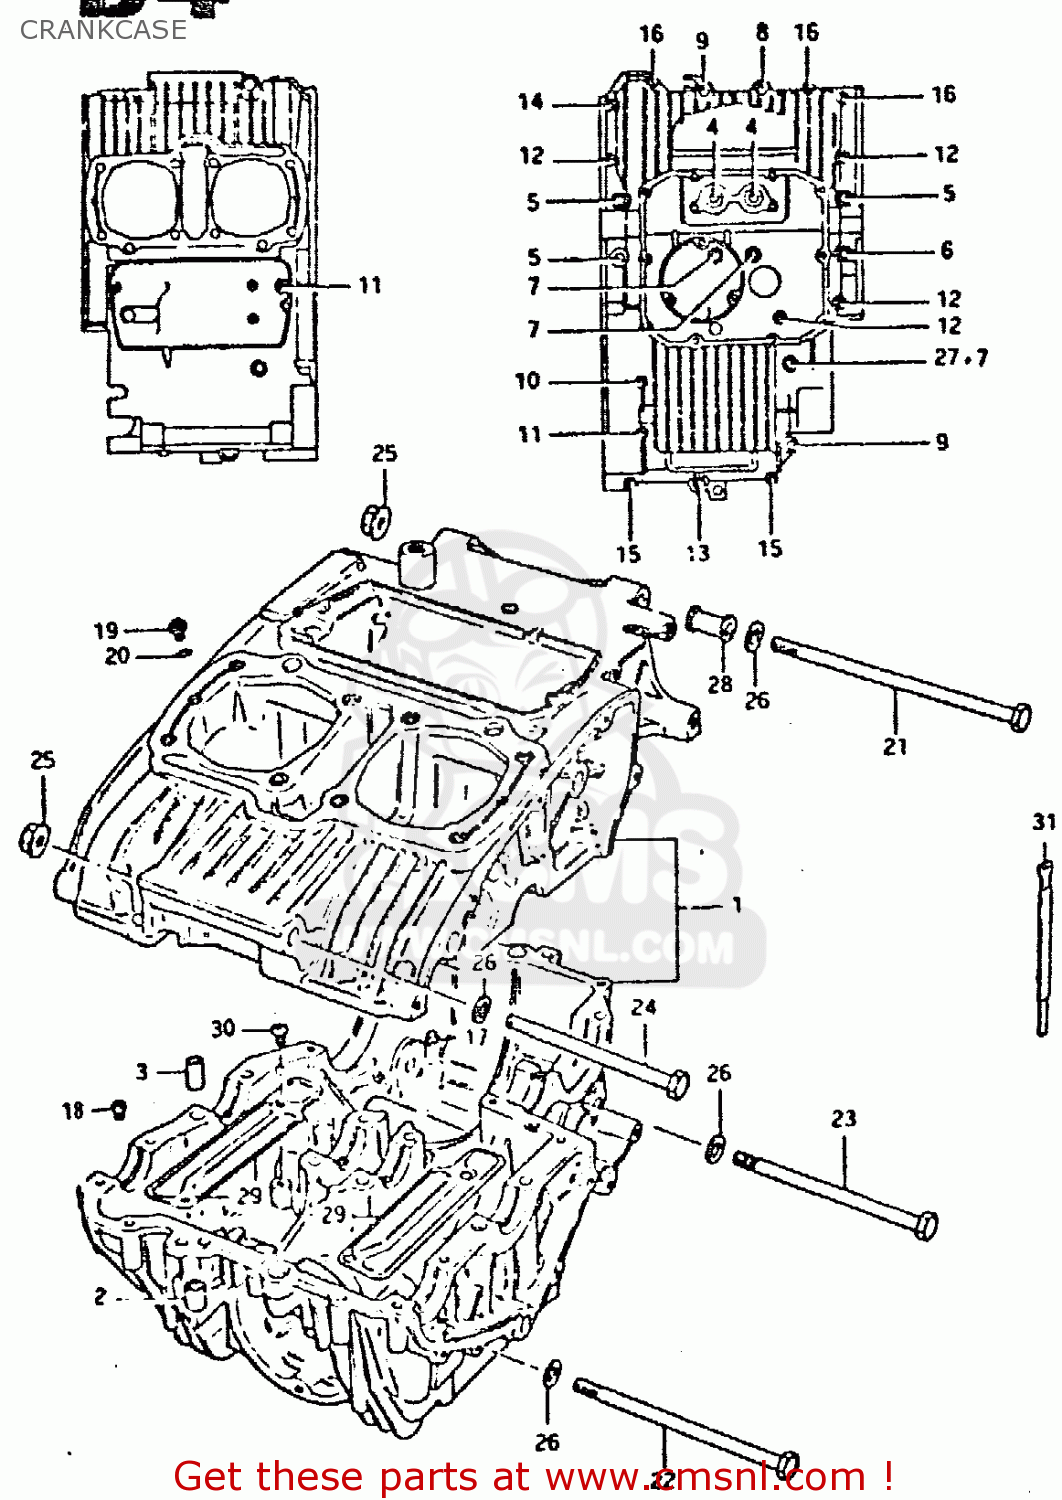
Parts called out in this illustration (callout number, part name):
1	CRANKCASE SET
2	PIN(10.4X13X22)
3	PIN (11X20)(SUS)
4	BOLT
5	BOLT
6	BOLT
7	BOLT
8	BOLT 8X65
9	BOLT (8X45)
10	BOLT
11	BOLT
12	BOLT (6X90)
13	BOLT (6X70)
14	BOLT 6X65
15	BOLT ,6X50
16	BOLT,UNDER
17	JET
18	JET
19	JET
20	O-RING
21	BOLT 10X250
22	BOLT(10X210)
23	BOLT 10X160
24	BOLT
25	NUT 10MM
26	WASHER
27	GASKET 8.2X14X1 (NAS)
28	SPACER,ENGINE MOUNT
29	PLATE,OIL SEPARATOR
30	SCREW
31	CLAMP
